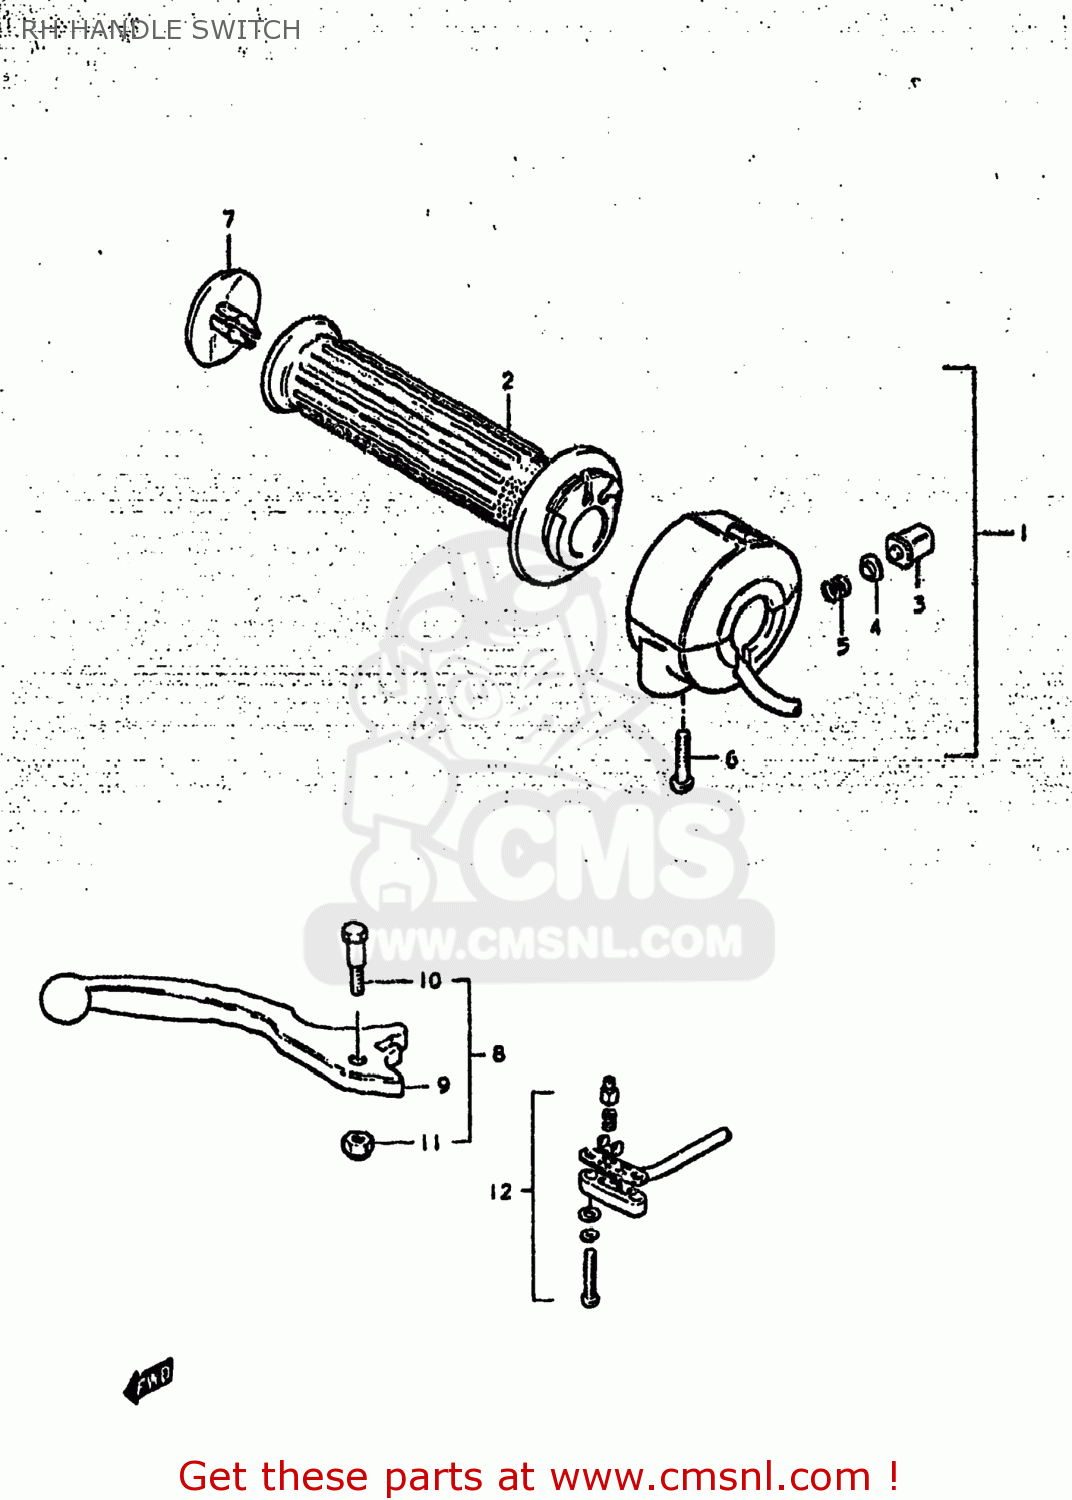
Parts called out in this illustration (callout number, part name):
1	CASE ASSEMBLY,THROTTLE
2	GRIP,THROTTLE
3	BUTTON,HORN
4	CONTACT
5	SPRING
6	SCREW
7	CAP,GRIP END
8	LEVER ASSEMBLY,BRAKE
9	LEVER,BRAKE
10	BOLT,LEVER
11	NUT 6MM
12	SWITCH ASSEMBLY
